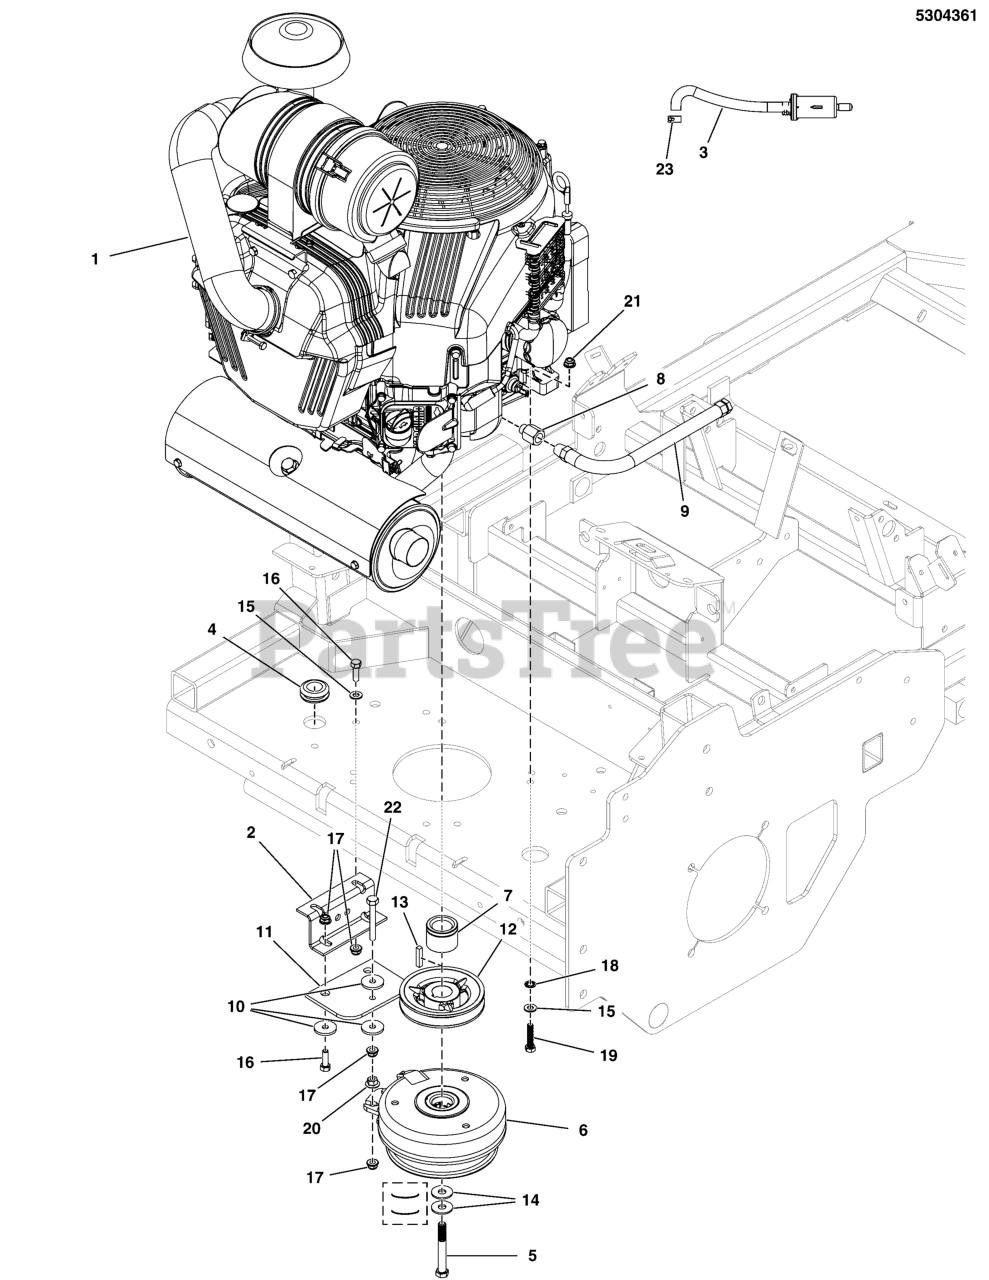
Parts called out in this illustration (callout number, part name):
2	ANCHOR, CLUTCH - BLK
3	HOSE/FILTER ASSY
4	GROMMET, 7/8"ID, 1/4" THICK STK
5	BOLT, CRANKSHAFT, 7/16-20 X 3-1/4, GD 8
6	CLUTCH, WARNER, 250 ft lbs - 1.13"
7	SPACER, 1.13 X 1.75 X 1.35, CZ
8	METRIC ADAPTER, M14-1.5" TO 3/8 NPTF
9	HOSE, OIL DRAIN
10	WASHER, .34 X 1.25 X 10 GA
11	CLUTCH ANCHOR PAD
12	PULLEY, 4.75 OD X 1-1/8 BORE, BC-48
13	KEY, 1/4 SQ X 1-1/4
14	BELLEVILLE WASHER 1.1875 X .442 X .089
15	WASHER, 5/16" SAE
16	BOLT, 5/16-18 X 1 GD5 CZ
17	NUT, 5/16-18 HEX NYLOCK FLANGE
18	WASHER, 5/16 INT. TOOTH LOCK
19	BOLT, 5/16-24 X 1-3/4, GD8, PHOS
20	NUT, 5/16-18 HEX SERRATED FLANGE (LARGE)
21	NUT, 5/16-24, TOP LOCK FLANGE, GD8 PHOS
22	BOLT, 5/16-18 X 2-1/2 GD5 TFL, CZ
23	CLAMP, HOSE, EXTERNAL, 9/16
